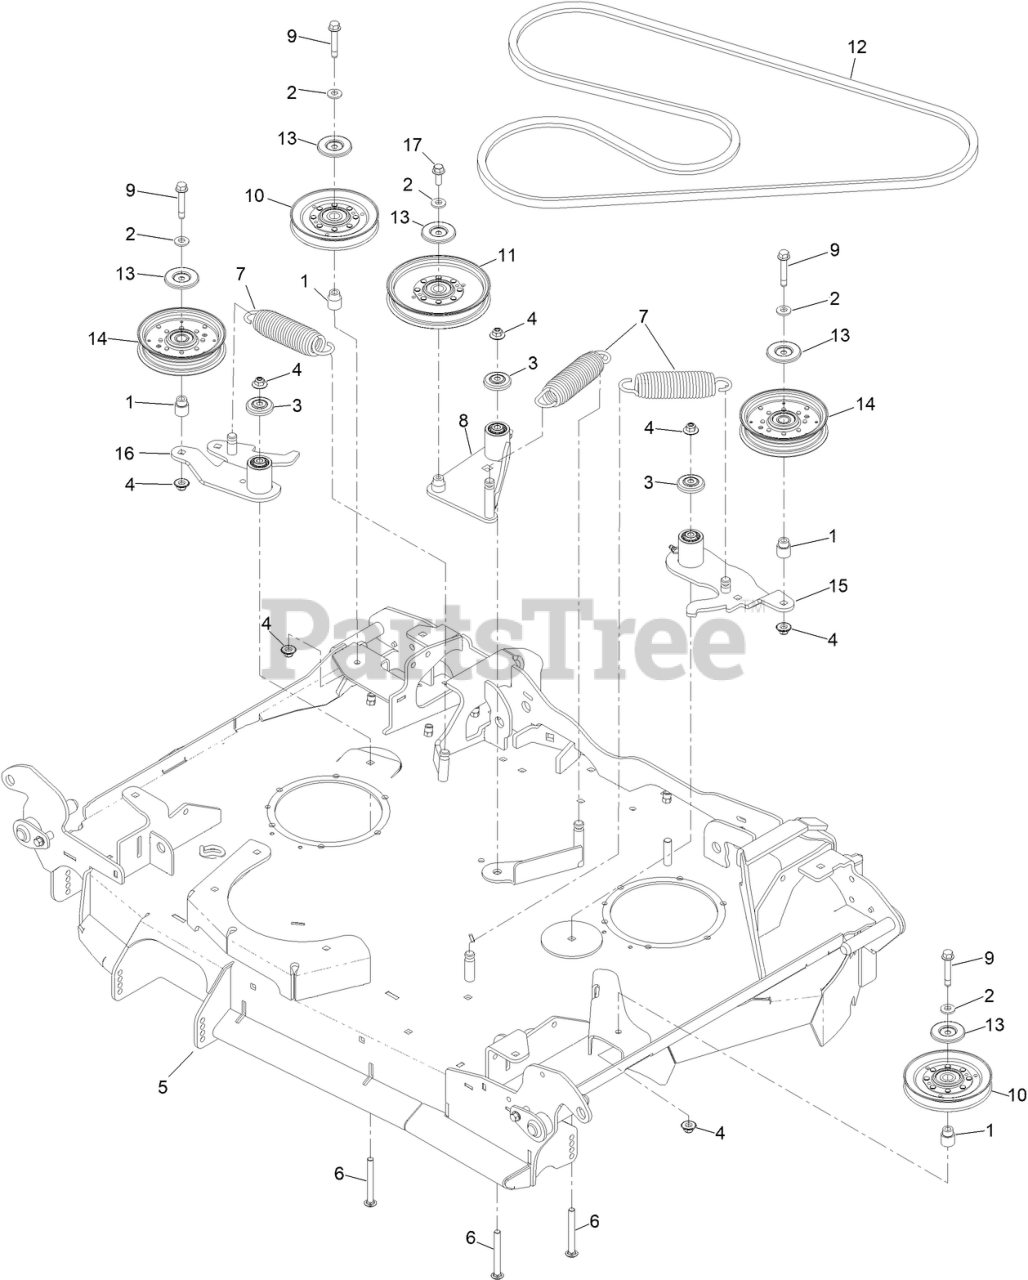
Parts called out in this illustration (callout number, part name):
1	BUSHING-IDLER
2	WASHER-BELLEVILLE
3	GUARD-TOP
4	NUT-FLANGE, NI
5	ASM-DECK, CTR 96T
6	BOLT-SHOULDER, CARRIAGE
7	SPRING-EXTENSION
8	IDLER ARM ASM
9	SCREW-HHF W/ PATCH
10	IDLER-V
11	IDLER-PULLEY
12	V-BELT
13	SHIELD-DUST
14	PULLEY-IDLER, FLAT
15	IDLER ASM
16	IDLER ASM
17	SCREW-HHF
